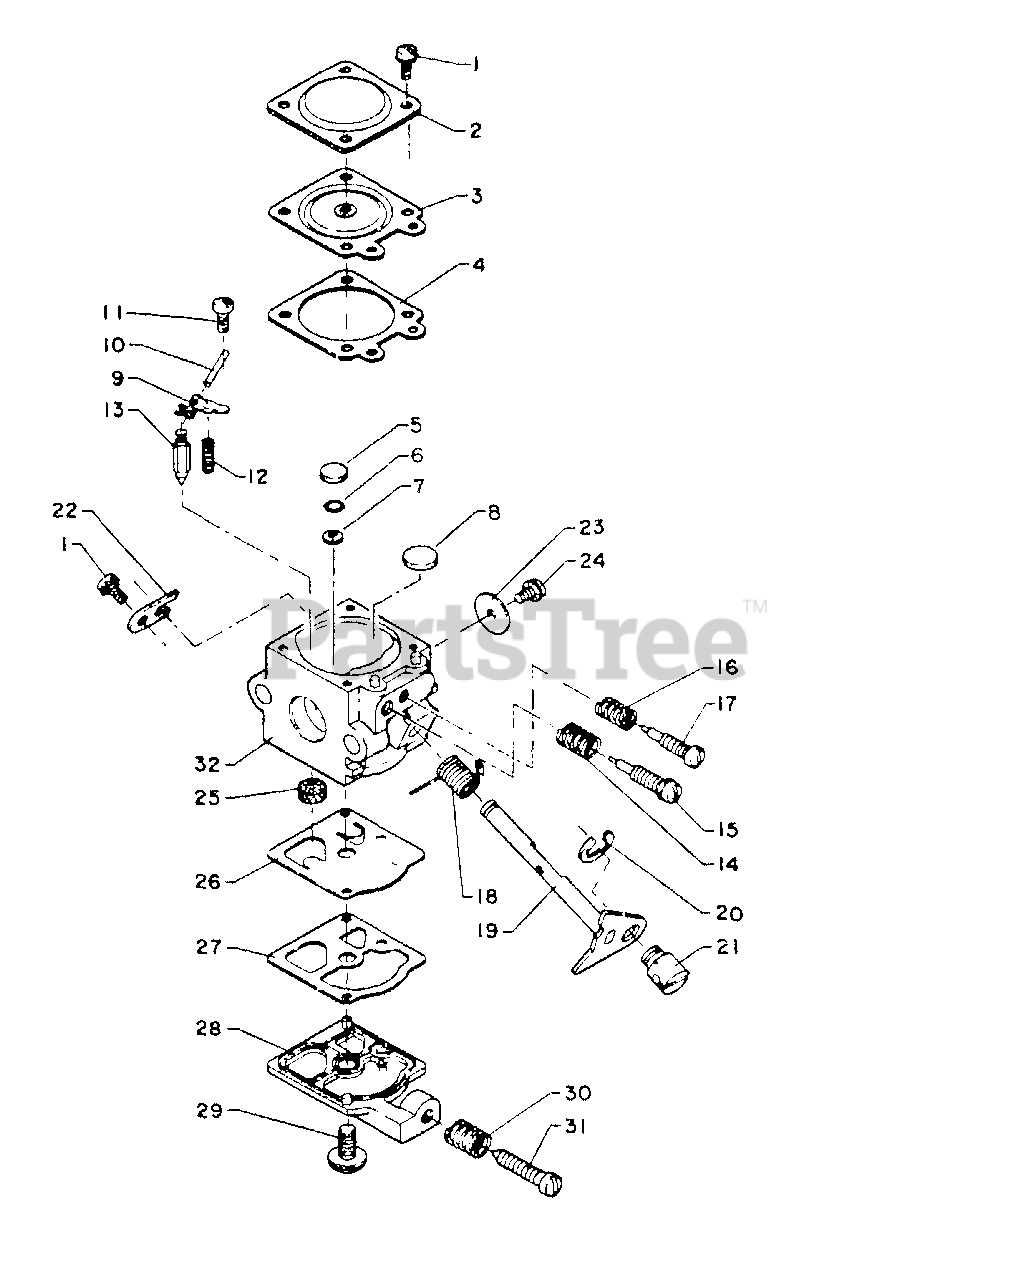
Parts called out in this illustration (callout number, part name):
2	COVER, METERING DIAPHRAGM
3	DIAPHRAGM, METERING
4	GASKET, METERING
5	PLUG, WELCH
6	RING, RETAINING
7	SCREEN, SPARK ARRESTER
8	PLUG, WELCH
9	LEVER, METERING
10	PIN, METERING LEVER
11	SCREW, METERING LEVER PIN
13	VALVE, INLET NEEDLE
14	SPRING, NEEDLE
15	NEEDLE, HIGH SPEED
16	SPRING, NEEDLE
17	NEEDLE, LOW SPEED
18	SPRING, THROTTLE RETURN
19	SHAFT, THROTTLE
20	RING, RETAINING
22	CLIP, THROTTLE SHAFT
23	VALVE, THROTTLE
25	SCREEN, FUEL INLET
26	DIAPHRAGM, PUMP
27	GASKET, FUEL PUMP
28	COVER, PUMP
30	SPRING, IDLE ADJUST
31	SCREW, IDLE ADJUST
32	BODY, CARBURETOR
